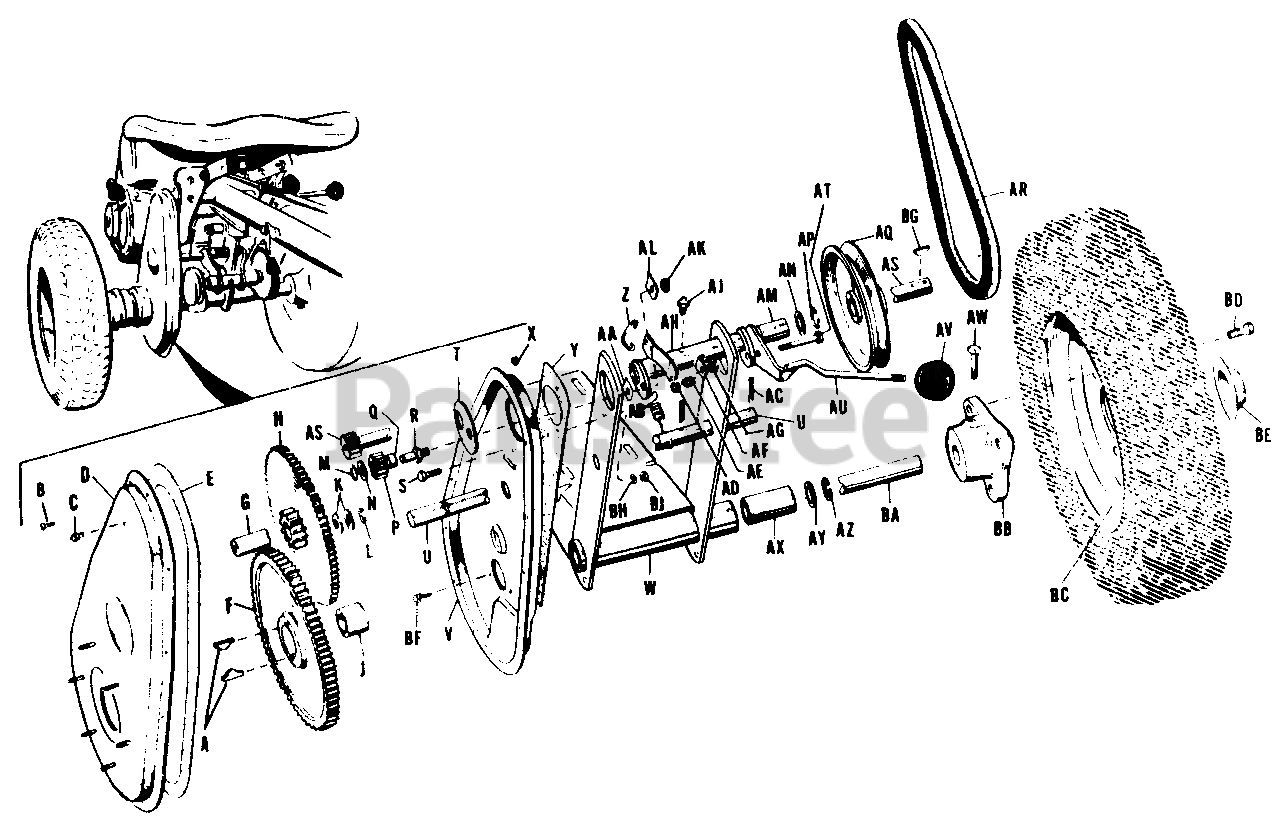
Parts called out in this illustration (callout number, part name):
A	Key, Hi-Pro, HP-108
B	Screw, Rd. Hd. Mach. 10-32 x 3/8"
C	Grease Fitting No. AD-1051
D	Cover Assembly
E	Gasket Case
F	Gear Assembly, Drive
G	Bearing, Intermediate Pinion
H	Gear Assembly, Intermediate (available only as 2 gears assd.)
L	Ring, Retaining
M	Ring, Retaining
N	Washer, Reverse Pinion
P	Pinion Assembly, Reverse With Bearing
R	Stud, Reverse Pinion
S	Screw, Hex Cap 3/8-16 x 1"
U	Shaft, Intermediate
V	Case, Gear
W	Housing, Assembly, Axle
X	Nut, Hex Lock No. 10-32
Y	Gasket, Bearing Housing
Z	Spring, Extension
AB	Spring, Reverse Lever
AC	Cotter Pin 3/16 x 1 1/4"
AD	Nut, Lock 3/8-16
AF	Plate, Friction
AG	Nut, Hex Jam 3/8-16
AH	Housing Assembly, Bearing
AJ	Grease Fitting No. 1911
AK	Nut, Hex, LH
AL	Plate, Lock
AP	Ring, Retaining
AQ	Pulley, Transmission
AR	Eng Drive "V" Belt A33S Super Combine 35" Long
AS	Pinion and Pulley Shaft Assembly
AT	Screw, Hex Cap 3/8-16 x 1 3/4"
AU	Lever Assembly, Shift
AW	Screw, Set, Sq Hd. 3/8-16 x 1/4
AX	Bearing, Axle
AZ	Ring, Retaining
BA	Axle, Rear
BB	Hub, Wheel, L.H.
BC	Wheel, Less Tire and Tube à
BD	Bolt, Hub
BE	Cap, Hub, Rear
BF	Screw, Cap 5/16-18 x 3/8"
BG	Key, Woodruff, 3/16 x 3/4
BH	Washer, Lock 3/8
BJ	Nut, Hex, Full 3/8-16
AA	Gun, Grease Wrench, Set Screw-5,32"
